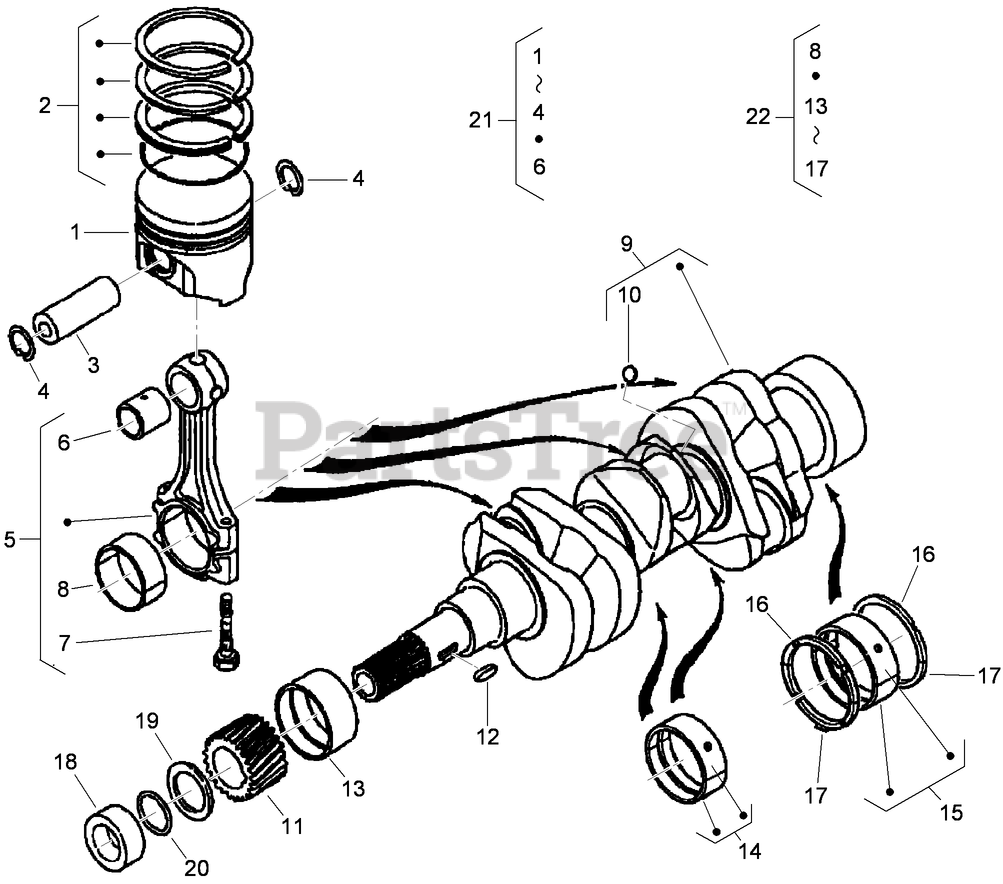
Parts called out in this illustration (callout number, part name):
2	PISTON RING ASM (STD)
2	PISTON RING ASM (+.25MM)
3	PIN-PISTON
4	CIRCLIP-INTERNAL
6	BUSHING-PIN, PISTON
7	BOLT-ROD, CONNECTING
8	METAL-CRANKPIN (STD)
9	CRANKSHAFT
11	GEAR-CRANKSHAFT
12	KEY-FEATHER
13	METAL-CRANKSHAFT (STD)
13	METAL-CRANKSHAFT (-.0.20MM)
13	METAL-CRANKSHAFT (-0.40MM)
14	CRANKSHAFT METAL ASM (STD)
14	CRANKSHAFT METAL ASM (-0.20MM)
14	CRANKSHAFT METAL ASM (-0.40MM)
15	CRANKSHAFT METAL ASM (-0.20MM)
15	CRANKSHAFT METAL ASM (-0.40MM)
16	METAL-SIDE (STD)
16	METAL-SIDE (+0.20MM)
16	METAL-SIDE (+0.40MM)
17	METAL-SIDE (STD)
17	METAL-SIDE (+0.20MM)
17	METAL-SIDE (+0.40MM)
18	COLLAR-CRANKSHAFT
19	SLINGER-OIL
20	O-RING
21	PISTON KIT (STD)
22	ENGINE METAL KIT
